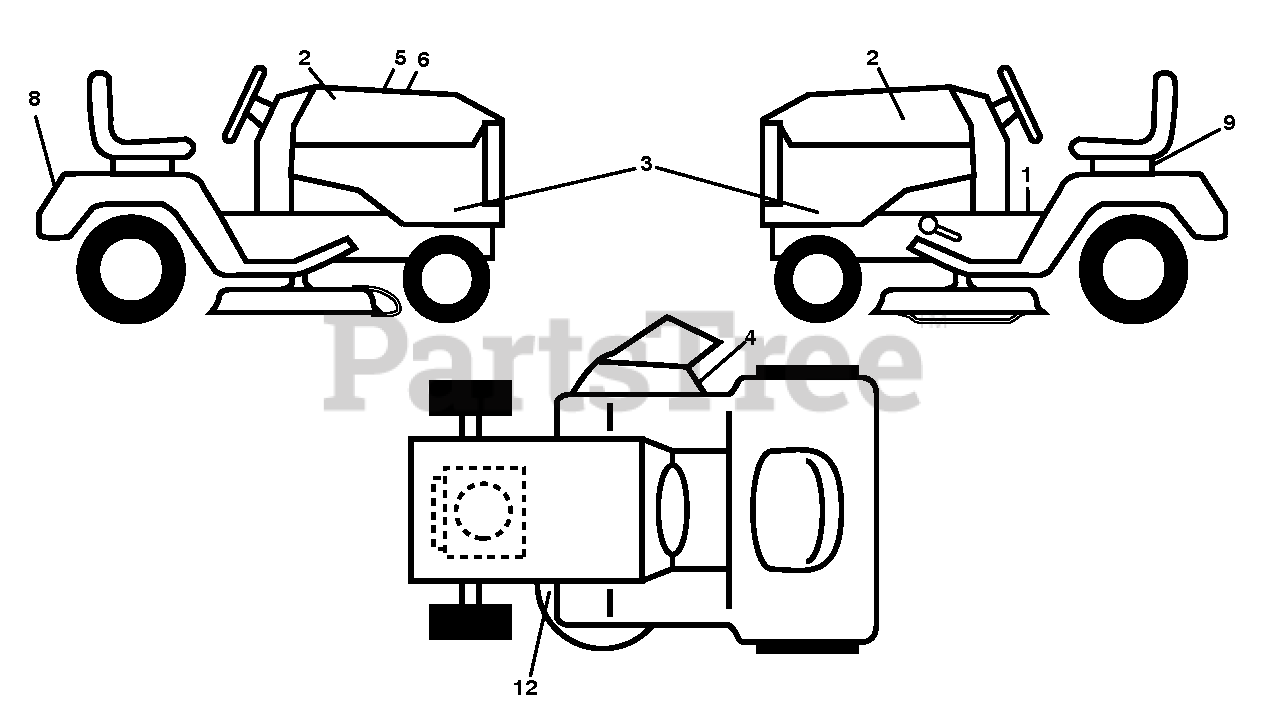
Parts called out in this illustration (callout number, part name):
1	DECAL.WARN.START.INSTRUCTIONS
2	RP.DECAL.BADGE.170MM.TEXTLOGO
3	DECAL.SDPNL.HUSQGT2.YTH12K26.2
4	DECAL.WARN.KEEP.HAND.AWAY
5	DECAL.WARNING.CUST.RESP.E85.
6	Decal, Replacement 960450026
8	DECAL.FENDER
9	DECAL BTRY SYMBOLS
12	DECAL V BELT SCHEMATIC
